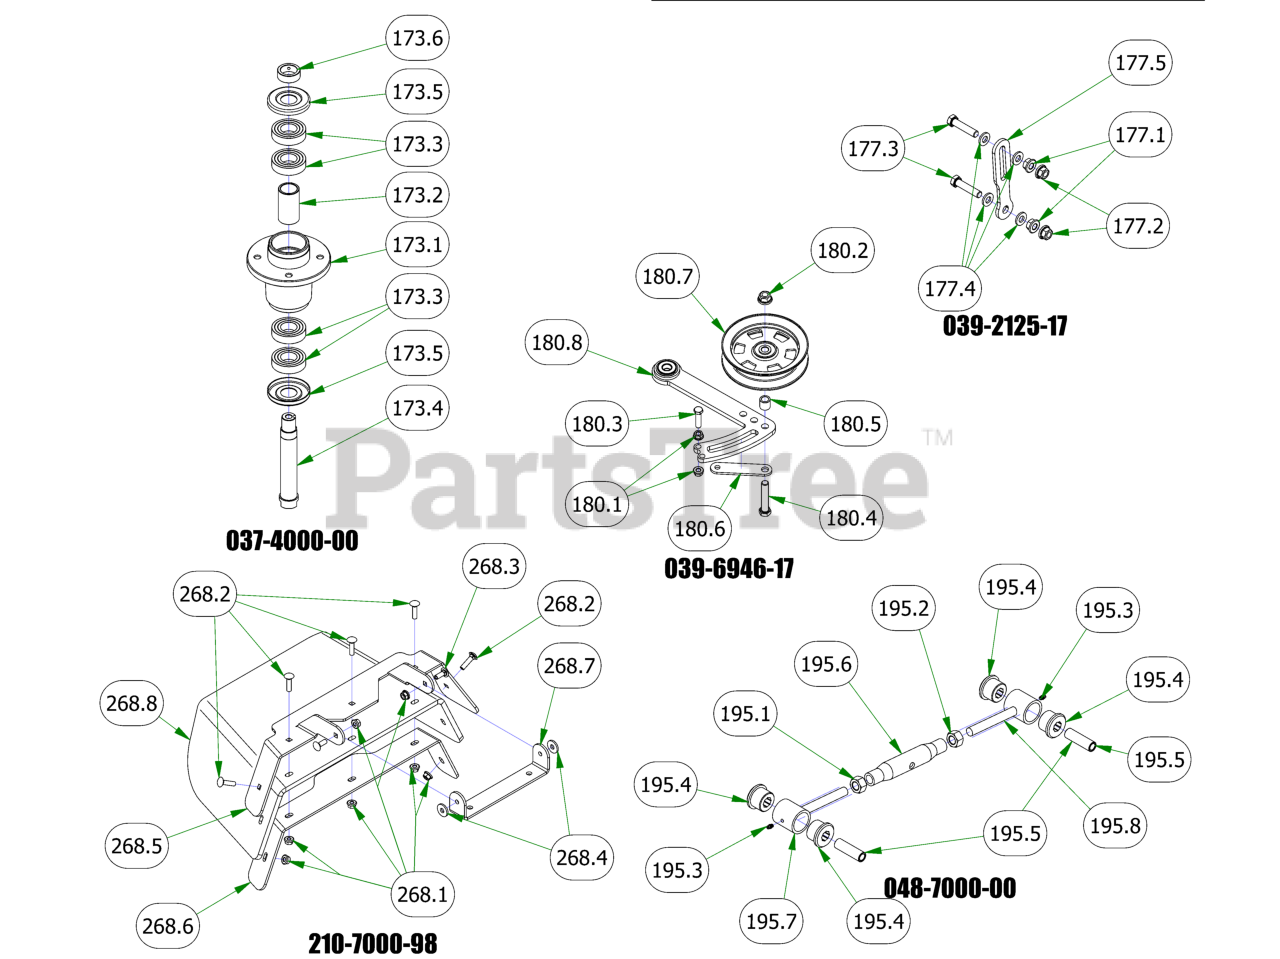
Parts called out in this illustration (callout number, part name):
173	OUTLAW SPINDLE ASSEMBLY
173.1	4000 Series Spindle Housing
173.2	4000 Series Spindle Spacer
173.3	Bearing - 6206
173.4	Spindle Shaft
173.5	Spindle Dust Cap
173.6	Locking Collar w/ 1/4"-20 Set Screw
177	Deck Hangar Assembly
177.1	1/2-13 HEX SERRATED FLANGE NUT HARD/ZINC
177.2	1/2-13 NYLON INSERT FLANGE LOCKNUT ZINC
177.3	1/2-13 X 2-1/4 HEX CAP SCREW (GR.5) ZINC
177.4	.505 ID X 1.000 OD X .125 THICK FLAT WASHER NYLON
177.5	Deck Hangar
180	2019 Renegade Deck Idler
180.1	3/8-16 HEX SERRATED FLANGE NUT HARD/ZINC
180.2	1/2-13 NYLON INSERT FLANGE LOCKNUT ZINC
180.3	3/8-16 X 1-1/2 HEX CAP SCREW (GR.5) ZINC
180.4	1/2-13 X 2-3/4 HEX CAP SCREW (GR.5) ZINC
180.5	.51 ID X .75 OD X .75 LGTH SOLID SPACER ZINC
180.6	Belt Tensioner Retainer Plate
180.7	5" Idler Pully
180.8	2019 Deck Tensioner
195	Turnbuckle
195.1	11/16-12 Hex Nut-2015 Toplink
195.2	11/16-12 Lefthand Hex Nut-Topl
195.3	1/4" Press in Grease Fitting
195.4	Polyeurethane Bushing
195.6	2015 Outlaw Toplink Body
195.7	2015 Outlaw Toplink RH End
195.8	2015 Outlaw Toplink LH End
268	2019 Outlaw Gen2 Chute Assembly
268.1	5/16-18 NYLON INSERT FLANGE LOCKNUT ZINC
268.2	5/16-18 X 1-1/4 CARRIAGE BOLT ZINC
268.3	5/16-18 X 7/8 CARRIAGE BOLT ZINC
268.4	.360 ID X .983 OD X .120 THICK FLAT WASHER NYLON
268.5	2019 Upper Chute Bracket
268.6	2019 Lower Chute Bracket
268.7	2019 Chute Hanger
268.8	2019 Belted Chute with Logo
